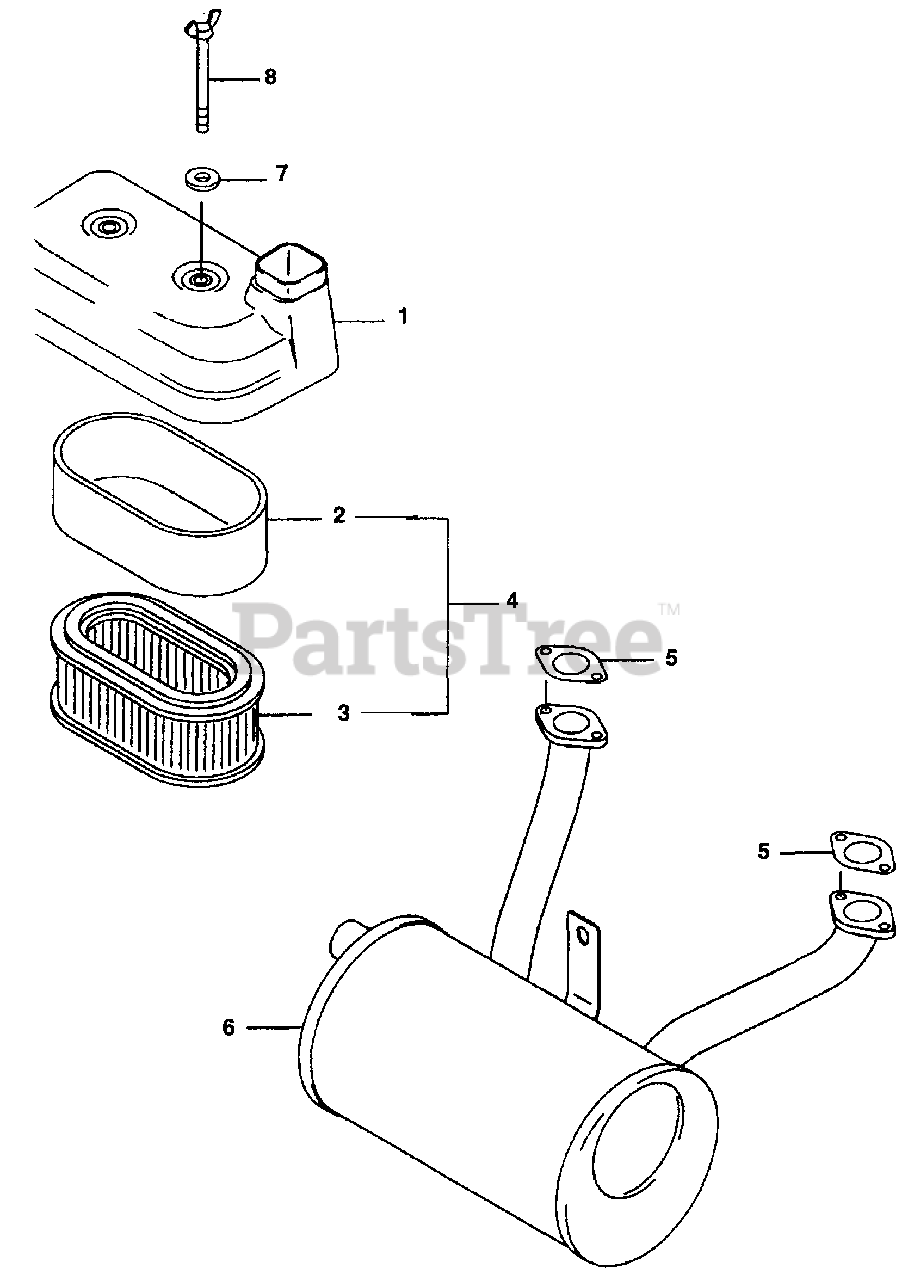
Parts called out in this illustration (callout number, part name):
1	Air Filter Case
2	Air Filter Element
3	Air Filter Element
4	Air Filter Element Ass'y
5	Muffler Gasket
